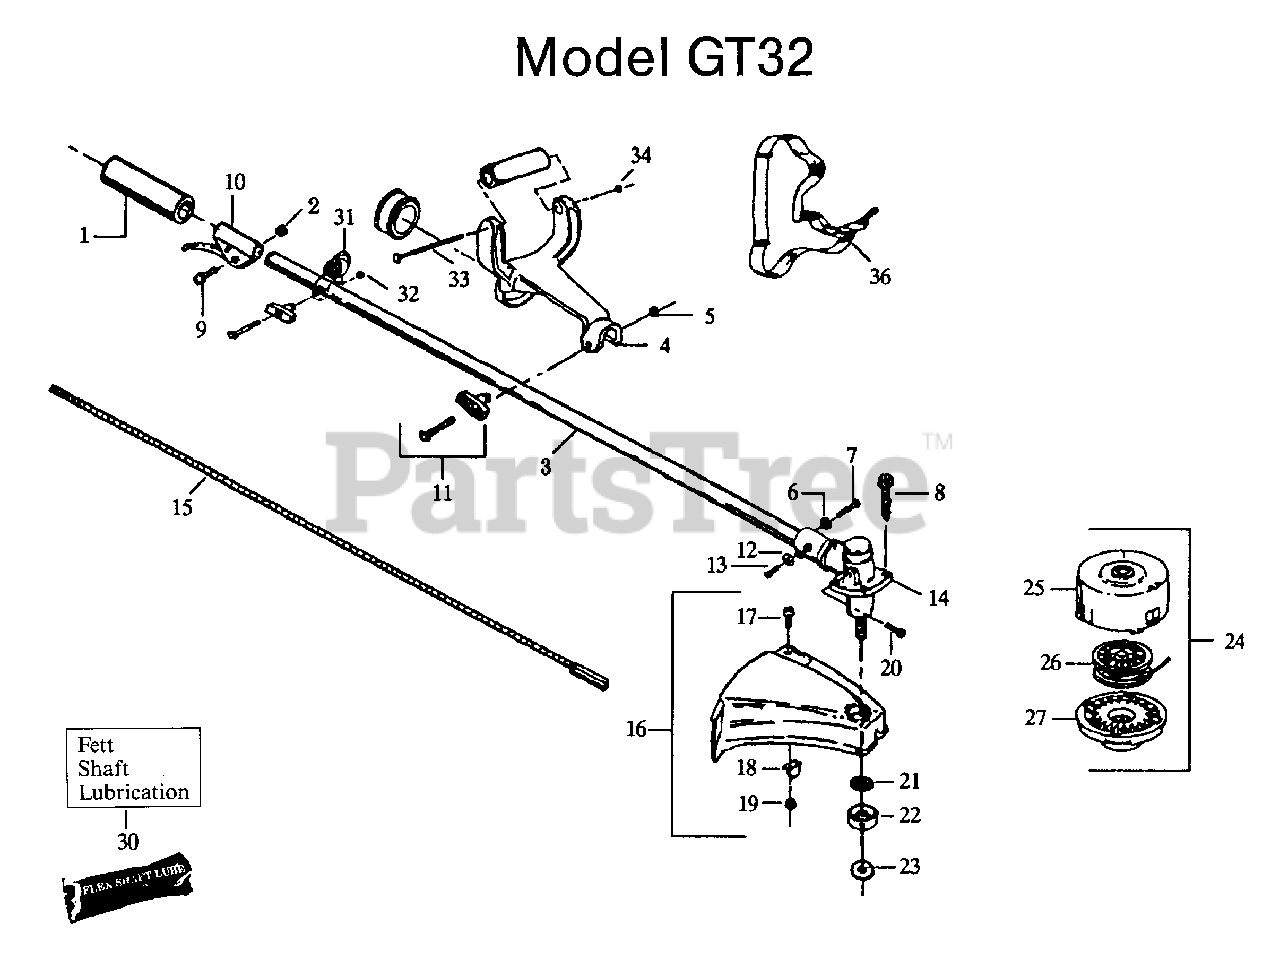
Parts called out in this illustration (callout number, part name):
1	GRIP-DRIVE SHAFT
2	LOCKNUT-HEX 10-24
3	DRIVE SHAFT HOUSING, TYPE 1
4	ASS'Y-HANDLE ANTIVIB
6	LOCKWASHER
7	SCREW-1/4-20X1 HEX SOC
8	SCREW-1/4-10X1-1/8 HEX
9	SCREW-10-24 X 1" (UNC)
10	ASSY-THROTTLE HOUSING
11	KIT "T" HANDLE
12	LOCKWASHER-LOCATOR-TYPE 2
13	SCREW-10-24 X 7/16 (HEX
14	GEAR BOX ASSY/TYPE 1
16	KIT-SHIELD
18	LIMITER-LINE
19	LOCKNUT-(10-24)
20	SCREW-5/16-24X3/8 HEX S
23	WASHER-GRASS
25	HUB ASSEMBLY
30	GREASE-1/2 FL. OZ.
31	ASSY-CLAMP HARNESS
32	NUT (1/4-20)
33	SCREW-12-24 X 4-11/16 P
34	NUT-12-24 (HEX)
36	STRAP SHOULDER
